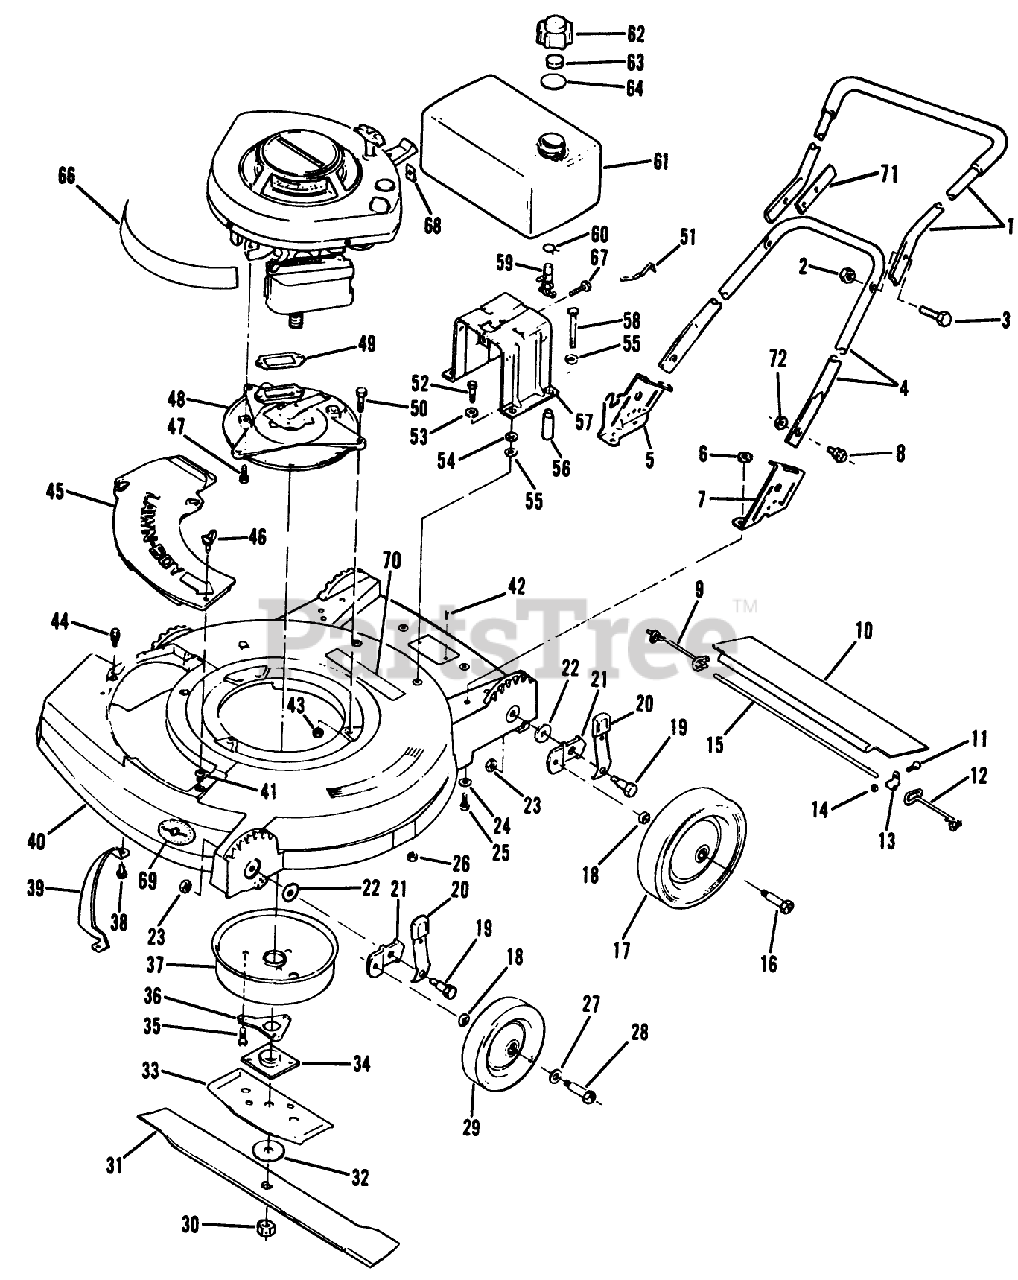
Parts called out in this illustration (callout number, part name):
1	Top Handle Grip Assy
2	LOCKNUT E
4	Handle Bottom
6	LOCKNUT E
9	SPRING;TRAILING SHIELD RH
12	SPRIG T/SHLD ASOC
13	CLAMP ROD KMC
14	LOCKNUT E
15	ROD 21" ADVANCE
16	BOLT-SHOULDER
18	WASHER WROUGHT
23	LOCKNUT
26	LOCKNUT E
28	BOLT WHEEL
30	NUT-BLADE
34	PLATE AND COLLAR ASM
36	SUPPORT F
39	BAR-TOE
43	NUT-LOCK F
46	WING SCREW LAWRE
47	SCREW V
58	BOLT PIONEER
59	VALVE&SCREEN SM
60	CLAMP - HOSE S
63	GASKET S
64	BAFFLE - FOAM SM
67	SCREW S
68	NUT-SPEED
72	NUT-JAM, LOCKING
